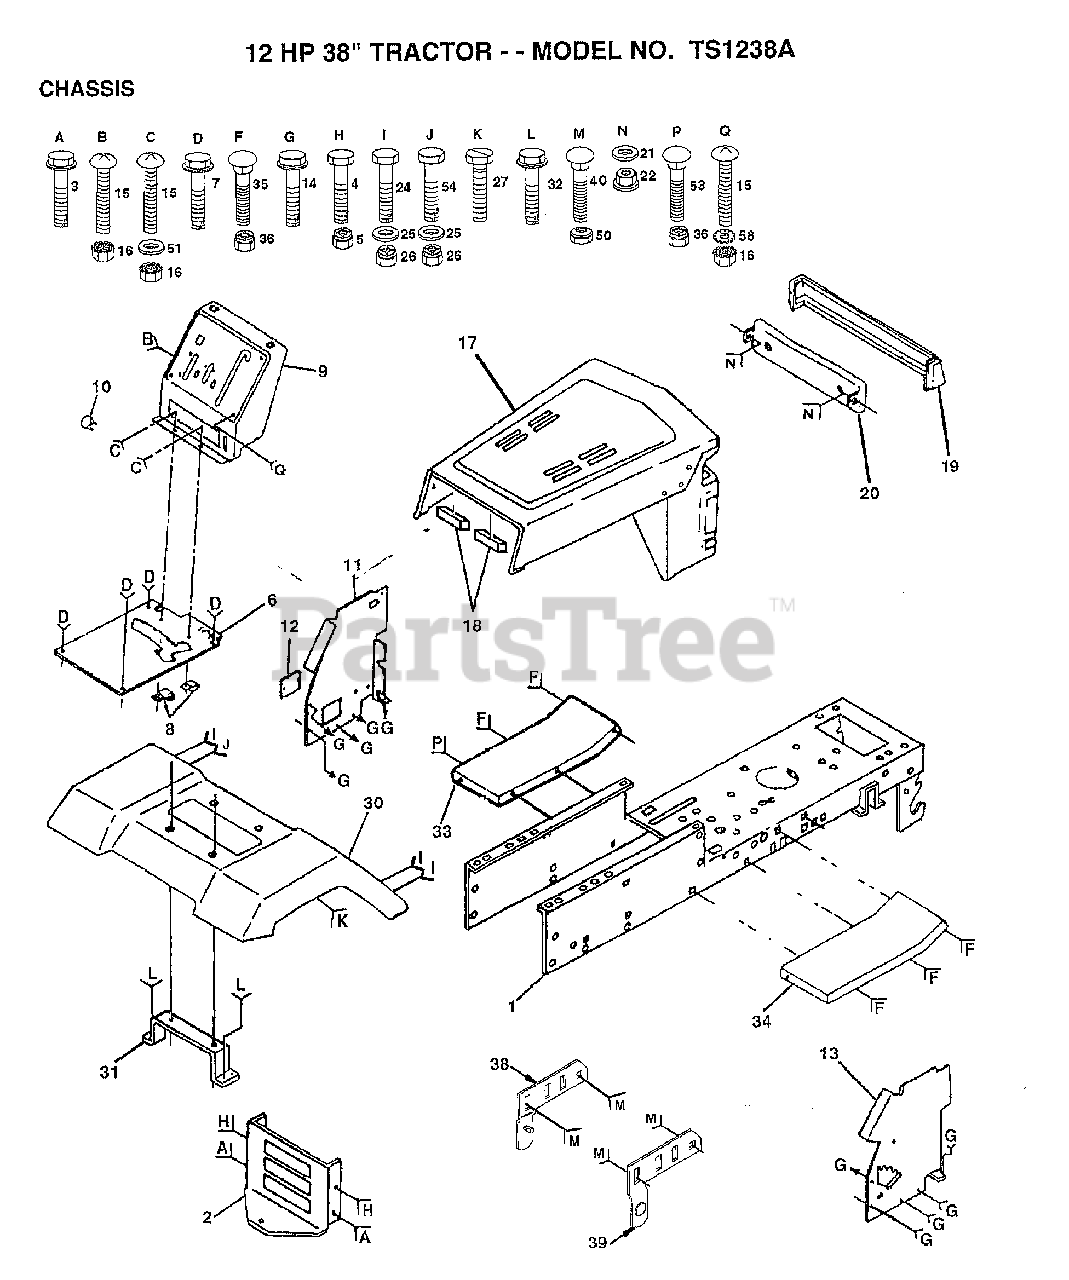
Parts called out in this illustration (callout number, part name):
3	SCREW
6	SADDLE. 5SP
7	SCREW LT
8	CLIP T
10	PLUG BUTTON T
11	PANEL DASH LH
12	COVER ACCESS
14	SCREW LT
15	SCREW
17	HOOD/GRILL ASM
19	LENS SERVICE KIT
21	WASHER PM
22	PAL NUT LT
25	WASHER
27	SCREW LT
30	FENDER
31	BRKT FENDER
32	SCREW
33	FOOTREST LH
34	FOOTREST RH
35	BOLT
38	BRKT ASM PIVOT LH
39	BRKT ASM PIVOT RH
50	NUT
51	WASHER
58	LOCKWASHER
